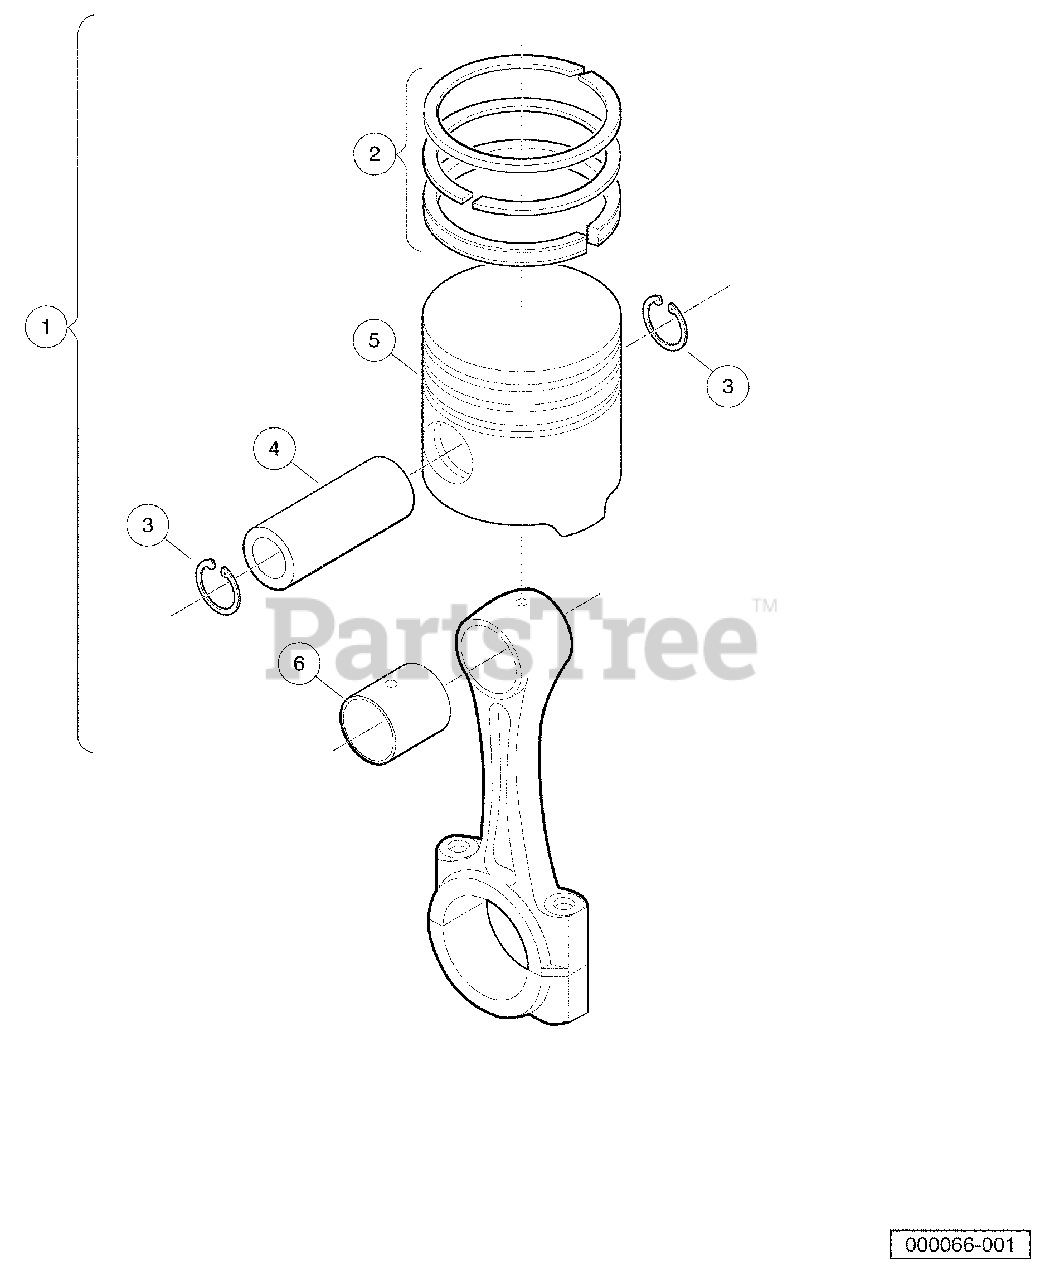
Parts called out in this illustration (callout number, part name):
1	Kit, Piston Rebuild, D722
2	Assy Piston Ring, D722 Std
3	Circlip, Piston Pin
4	Pin, Piston
5	Piston, D722, Std
6	Bushing, Piston Pin, D722
